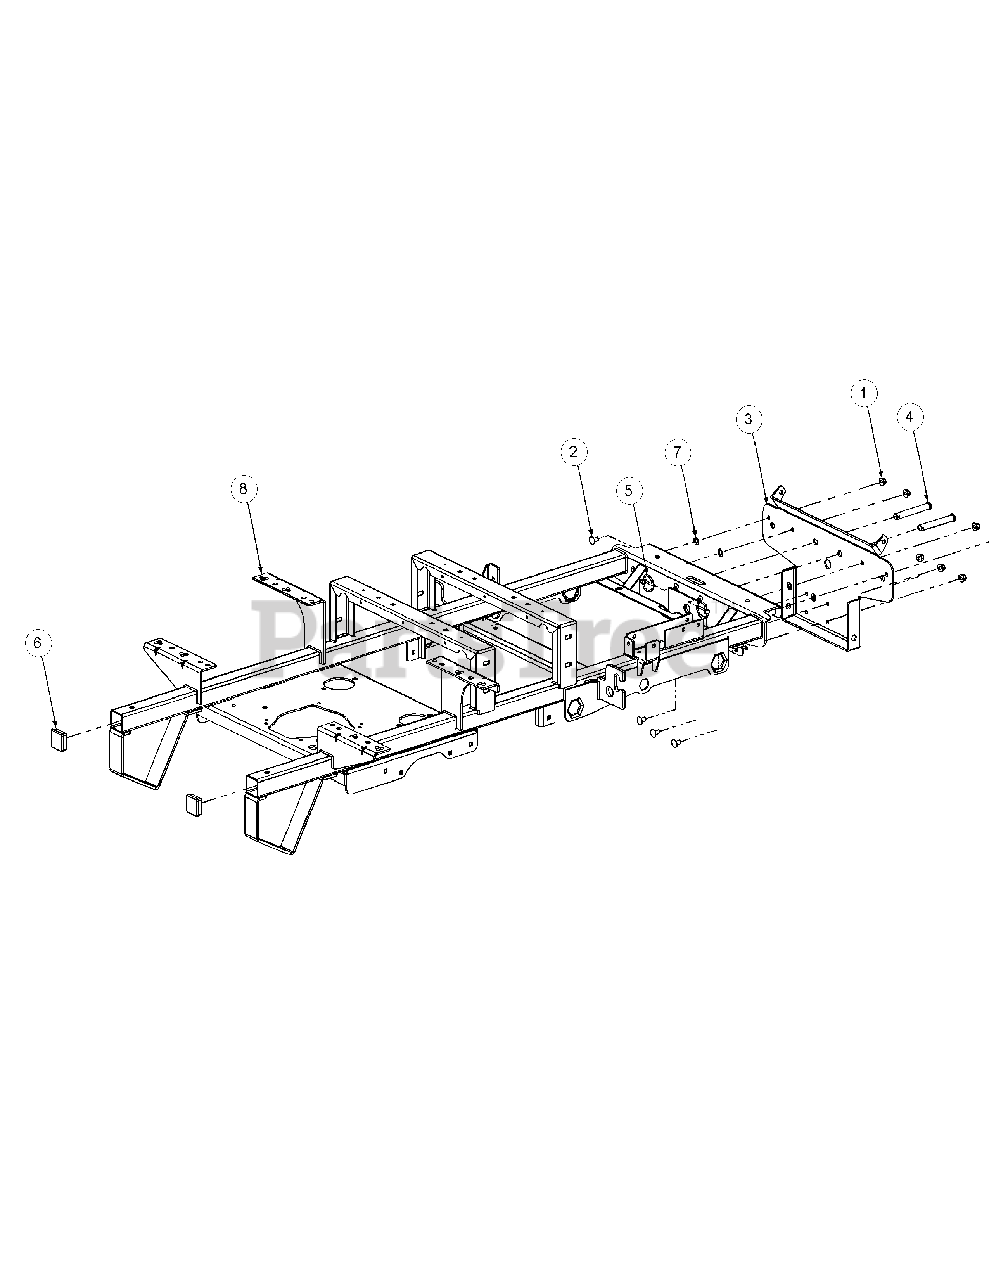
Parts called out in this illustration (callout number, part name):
1	Hex Nut, 3/8-16 Flange Lock
2	Carriage Bolt, 3/8-16 x .75 Long
3	Bracket Assembly, Frame, Front
4	Clevis Pin, .625 Dia x 4.375 Long
5	Linch Pin, 3/16 Dia.
6	Plug, Square Tube
7	Push Retainer, 3/8
8	Frame Assembly
